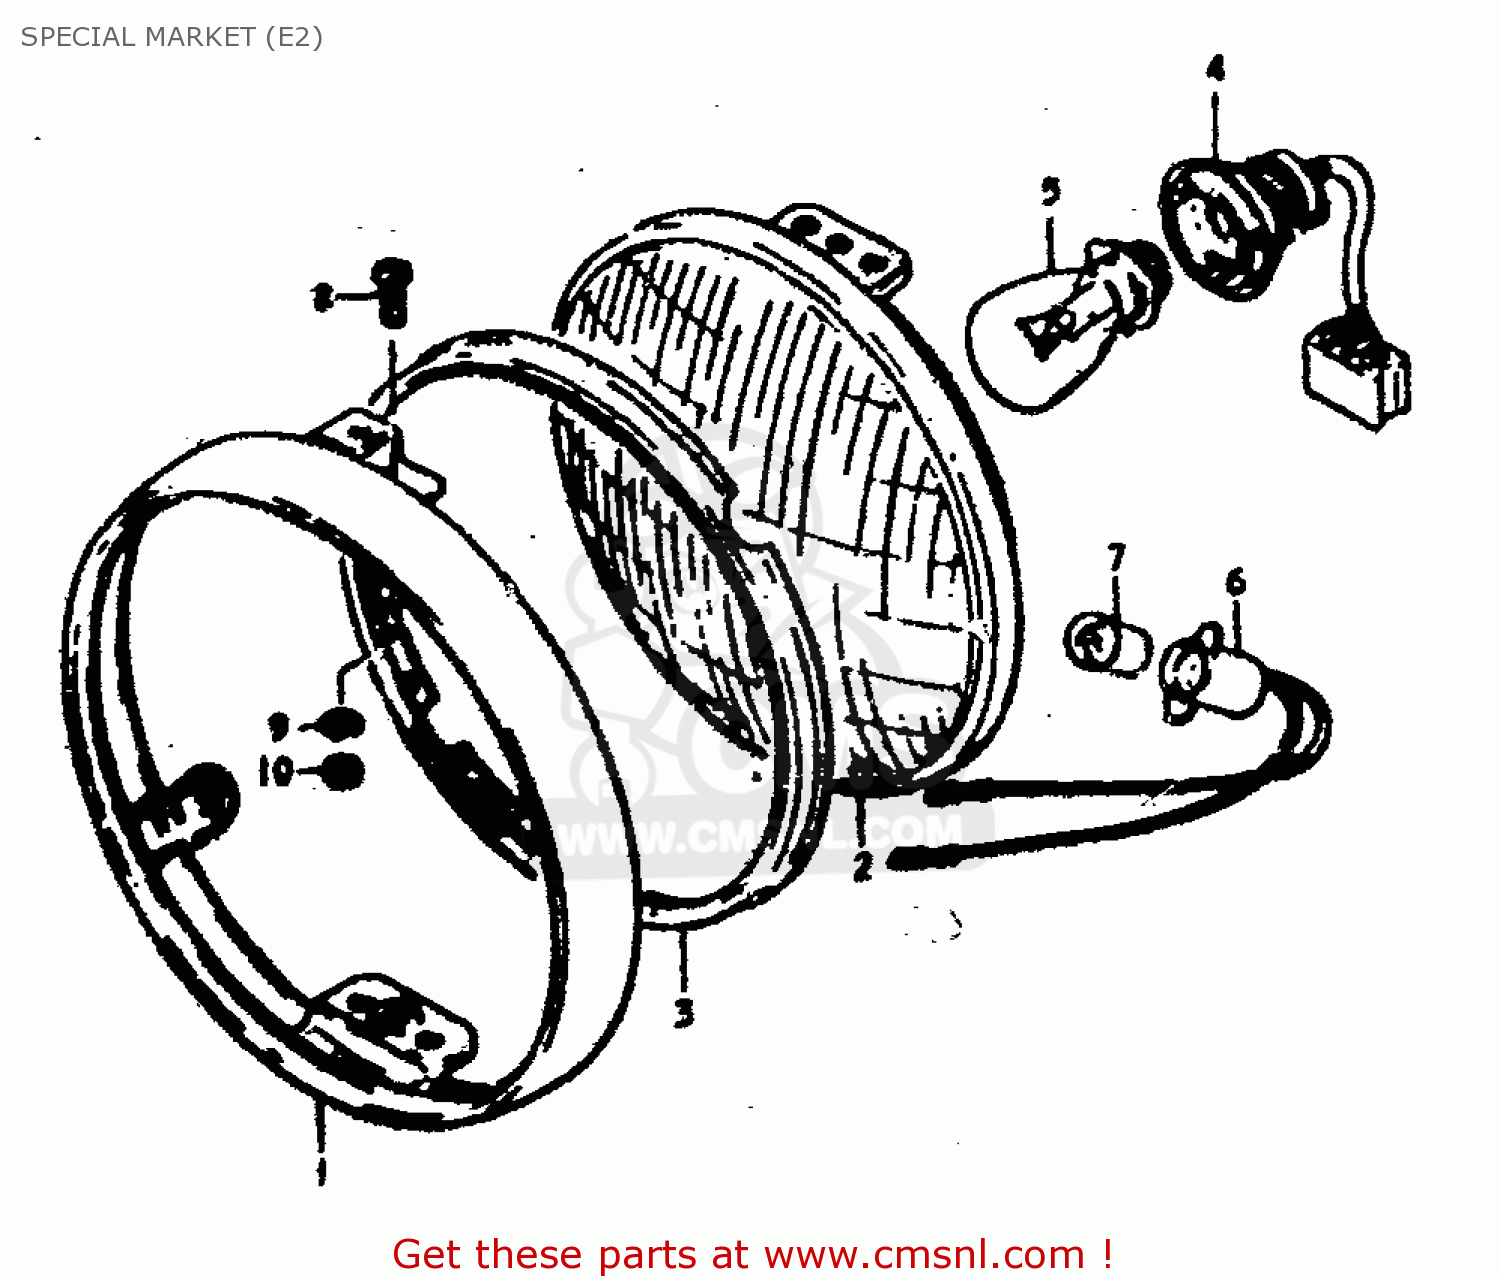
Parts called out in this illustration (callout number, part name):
1	RIM
2	UNIT
3	RETAINER,HEADLAMP
4	SOCKET
5	BULB 12V35/35W
6	SOCKET
7	BULB(12V3.4W,STANLEY,A72A)
8	SCREW
9	LOCK WASHER
10	NUT
